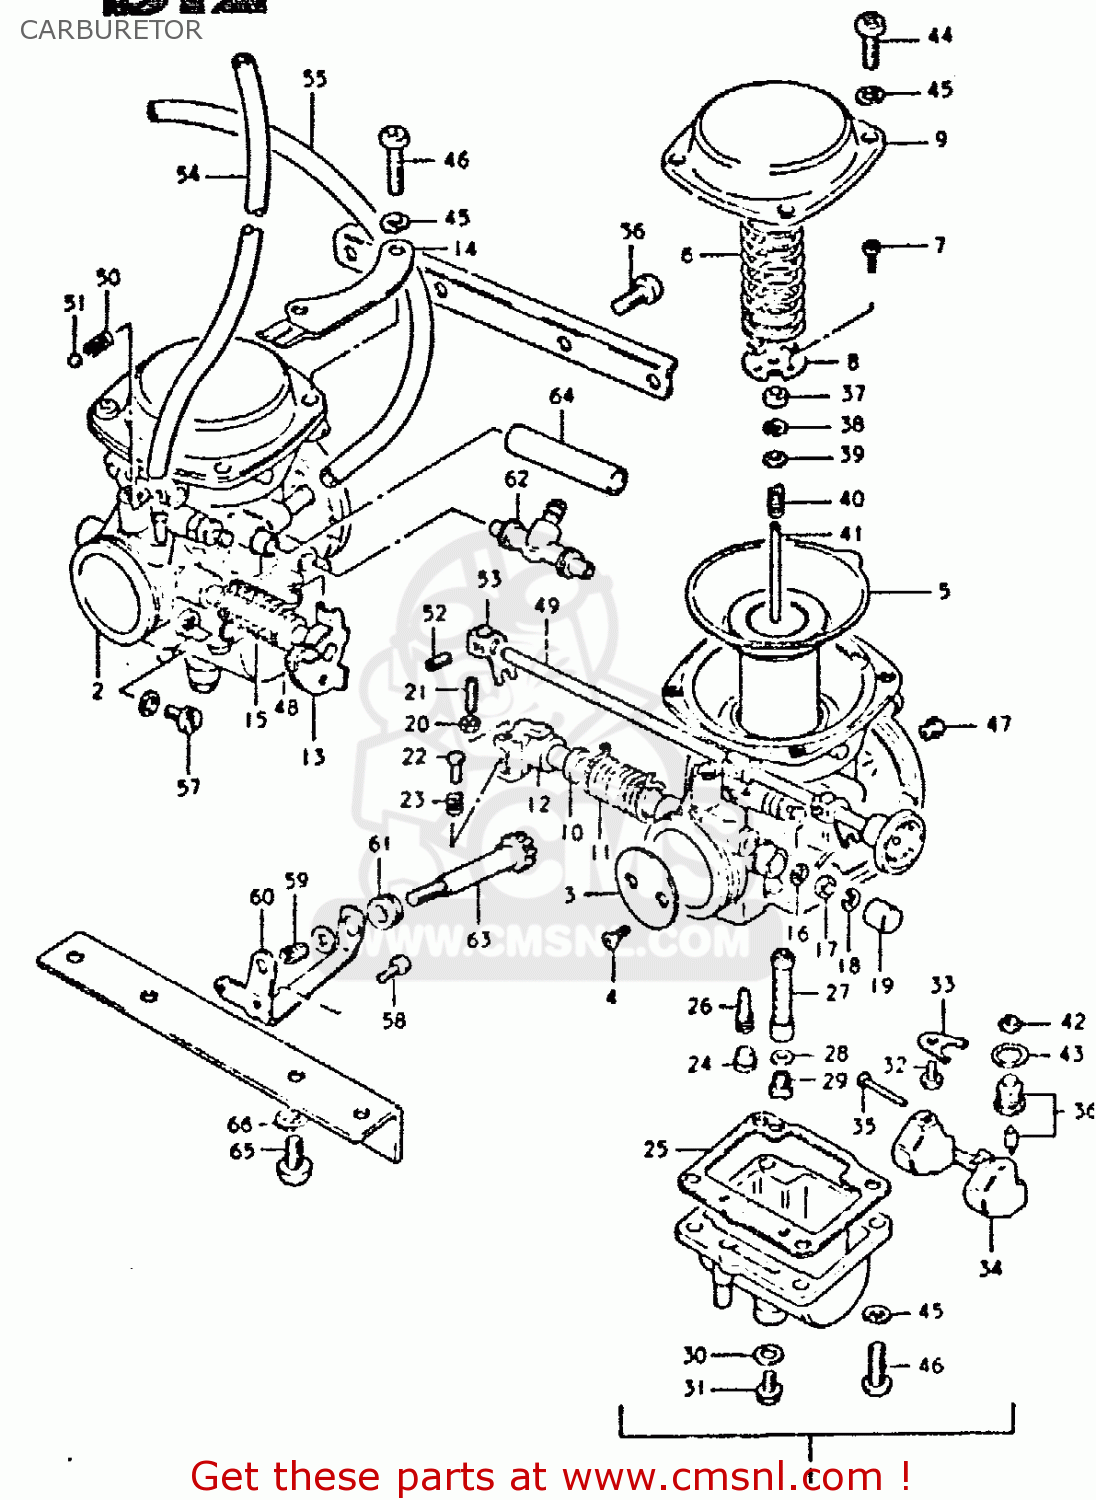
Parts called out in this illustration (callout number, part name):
1	CARBURETOR, LH
2	CARBURETOR, RH
3	VALVE, THROTTLE (135)
4	SCREW
5	DIAPHRAGM
6	SPRING
7	SCREW
8	PLATE
9	COVER,DIAPHRAGM
10	SPACER,THROTTLE SHAFT
11	SPRING
12	SHAFT
13	SHAFT,THROTTLE
14	BRACKET
15	SPRING
16	SEAL
17	GASKET,THROTTLE SHAFT (NAS)
18	E RING
19	CAP
20	NUT
21	SCREW
22	PIN,THROTTLE LEVER
23	SPRING,THROTTLE SCREW
24	PLUG,NEEDLE JET
25	GASKET,FLOAT CHAMBER (NAS)
26	JET, PILOT (42.5)
27	JET,NEEDLE(P-1)
28	WASHER,NEEDLE NOZZLE
29	JET
30	GASKET (NAS)
31	PLUG,DRAIN
32	SCREW 4X6
33	PLATE
34	FLOAT
35	PIN,FLOAT
36	VALVE ASSEMBLY,NEEDLE
37	RING
38	CLIP
39	PIN,FLOAT
40	SPRING
41	NEEDLE,JET
42	FILTER
43	O-RING,NEEDLE VALVE
44	SCREW
45	LOCK WASHER
46	SCREW
47	JET,AIR(125)
48	SPACER,THROTTLE SHAFT
49	SHAFT
50	SPRING
51	BALL,CARBURETOR
52	SCREW
53	LEVER
54	HOSE
55	HOSE
56	SCREW
57	SCREW
58	SCREW
59	SPRING
60	BRACKET,THROTTLE ADJUST
61	CAP
62	NIPPLE,CARBURETOR
63	SCREW
64	HOSE
65	SCREW 6X12
66	LOCK WASHER
